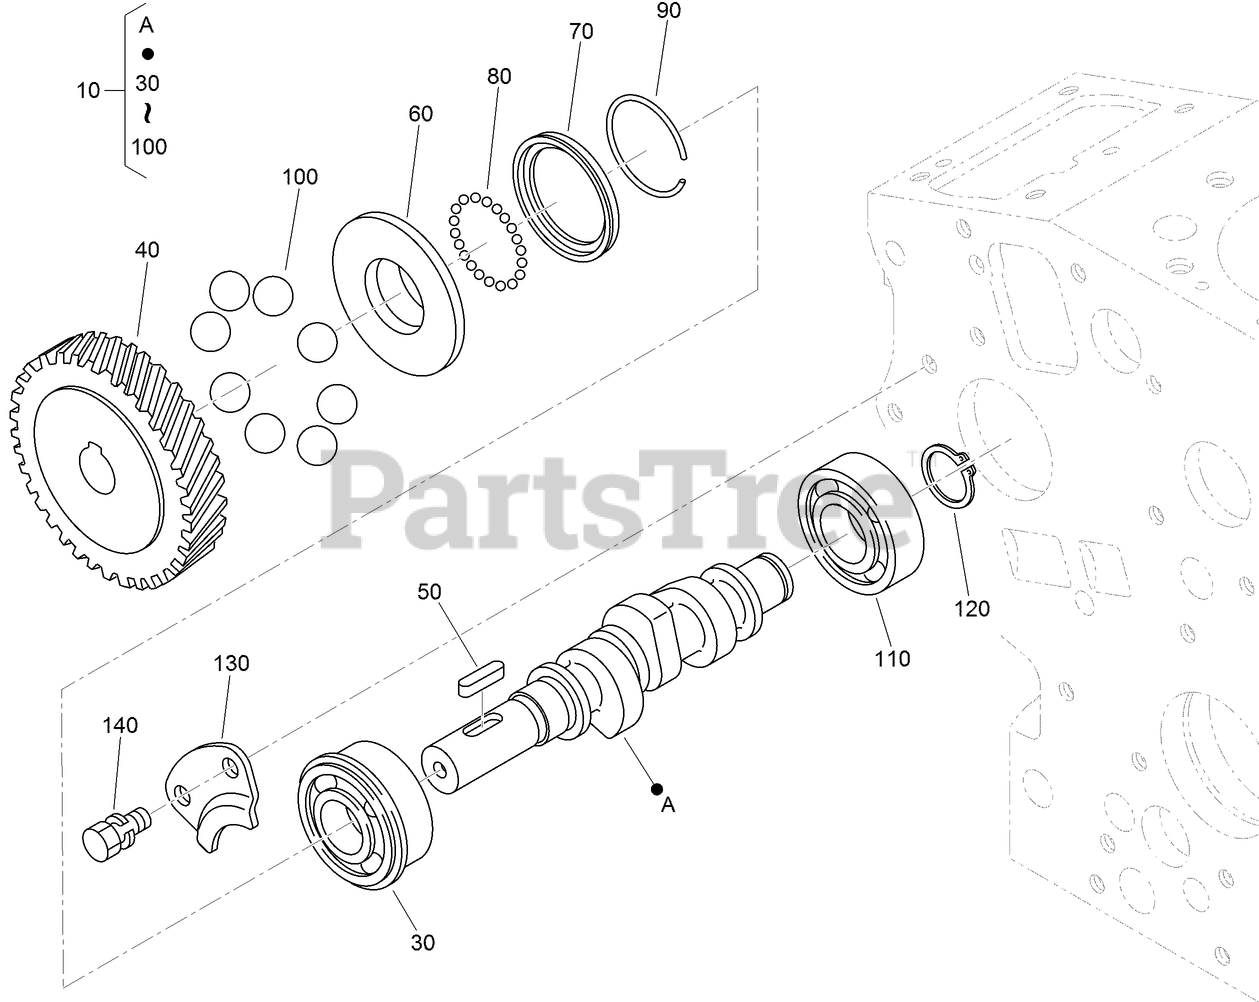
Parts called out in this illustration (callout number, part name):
10	FUEL CAMSHAFT ASM
30	BEARING-BALL
40	GEAR-PUMP, INJECTION
50	KEY-FEATHER
60	SLEEVE-GOVERNOR
70	CASE-BALL, GOVERNOR
90	CIRC-CLIP
110	BEARING-BALL
120	CIRC-CLIP, EXTERNAL
130	STOPPER-FUEL, CAMSHAFT
